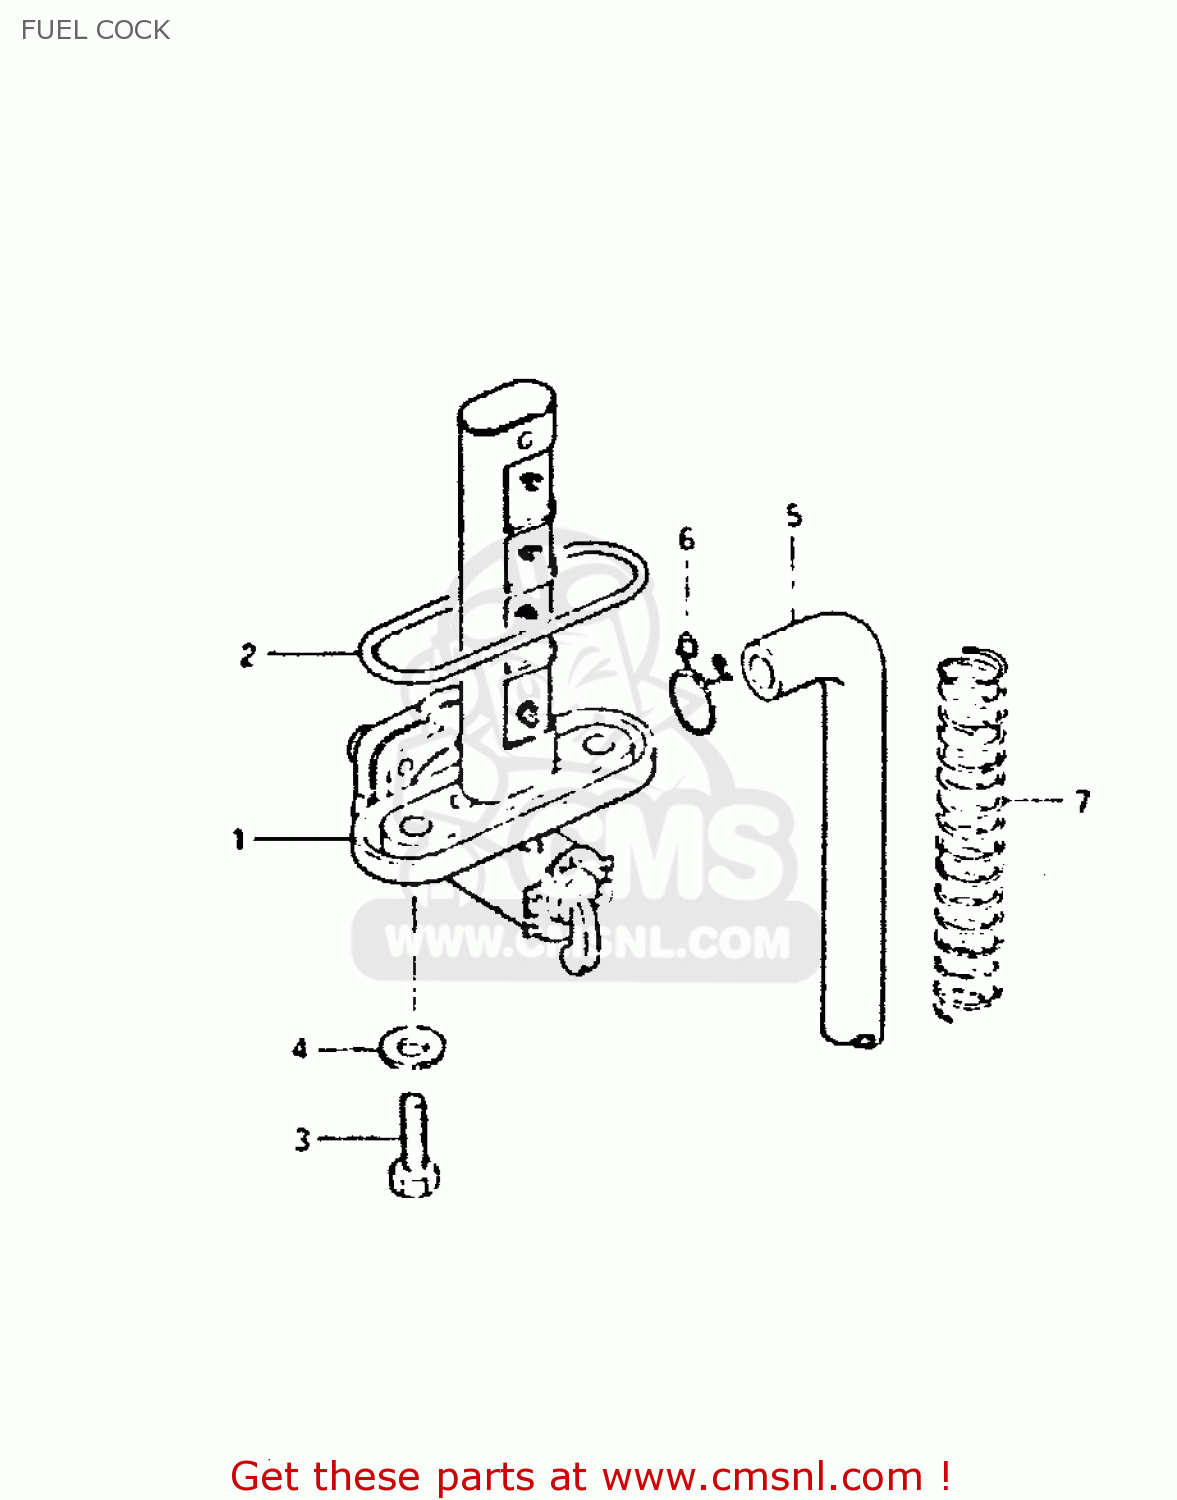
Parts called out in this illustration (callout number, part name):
1	COCK ASSEMBLY,FUEL
2	O RING
3	BOLT(6X20)
4	GASKET
5	HOSE
6	CLIP
7	SPRING
